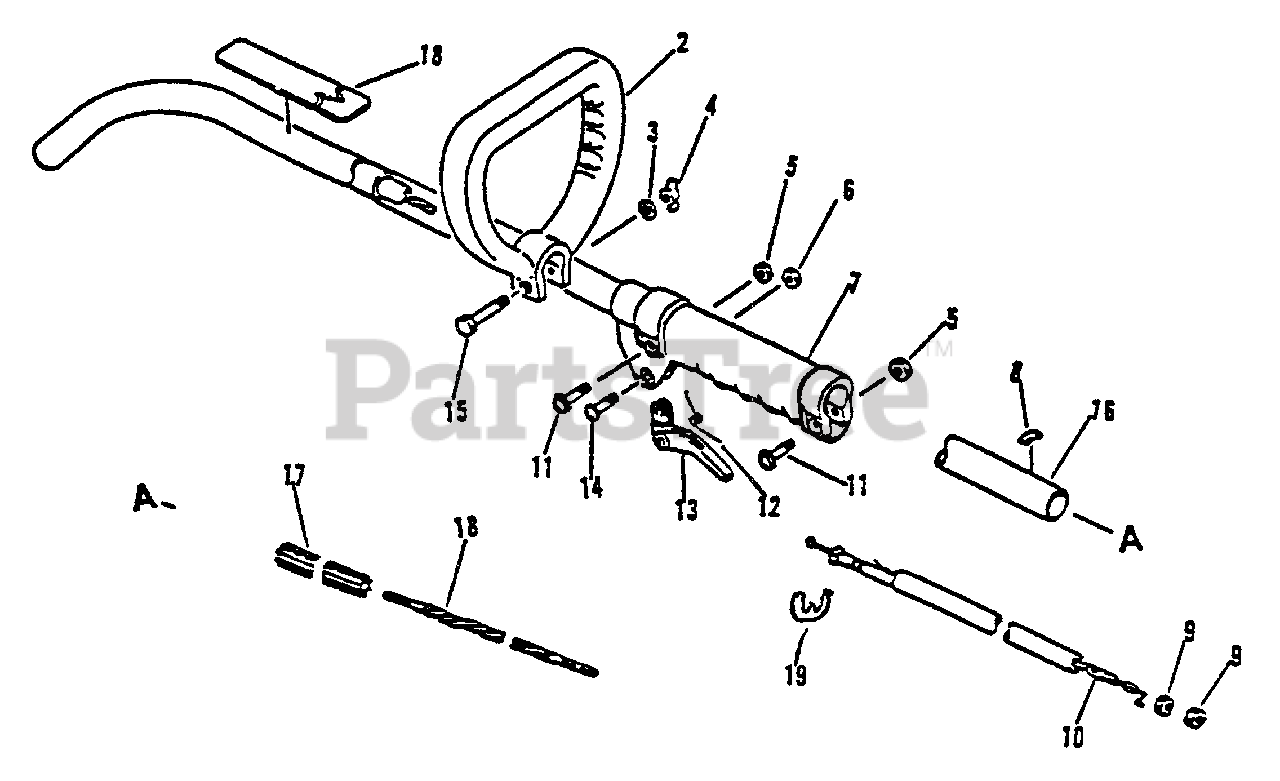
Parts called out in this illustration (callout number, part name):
2	HANDLE - FRONT
3	WASHER - 6
4	WINGNUT - 6
6	LOCKNUT - 5
7	GRIP, HANDLE
10	CABLE, THROTTLE
11	SCREW - 5X25
12	SPRING, TRIGGER
13	TRIGGER, THROTTLE
14	SCREW - 5X30
15	BOLT - 6X40
16	DRIVESHAFT - FLEXIBLE
17	LINER - FLEXIBLE
18	LABEL - CAUTION
19	RING, RETAINING - 5
